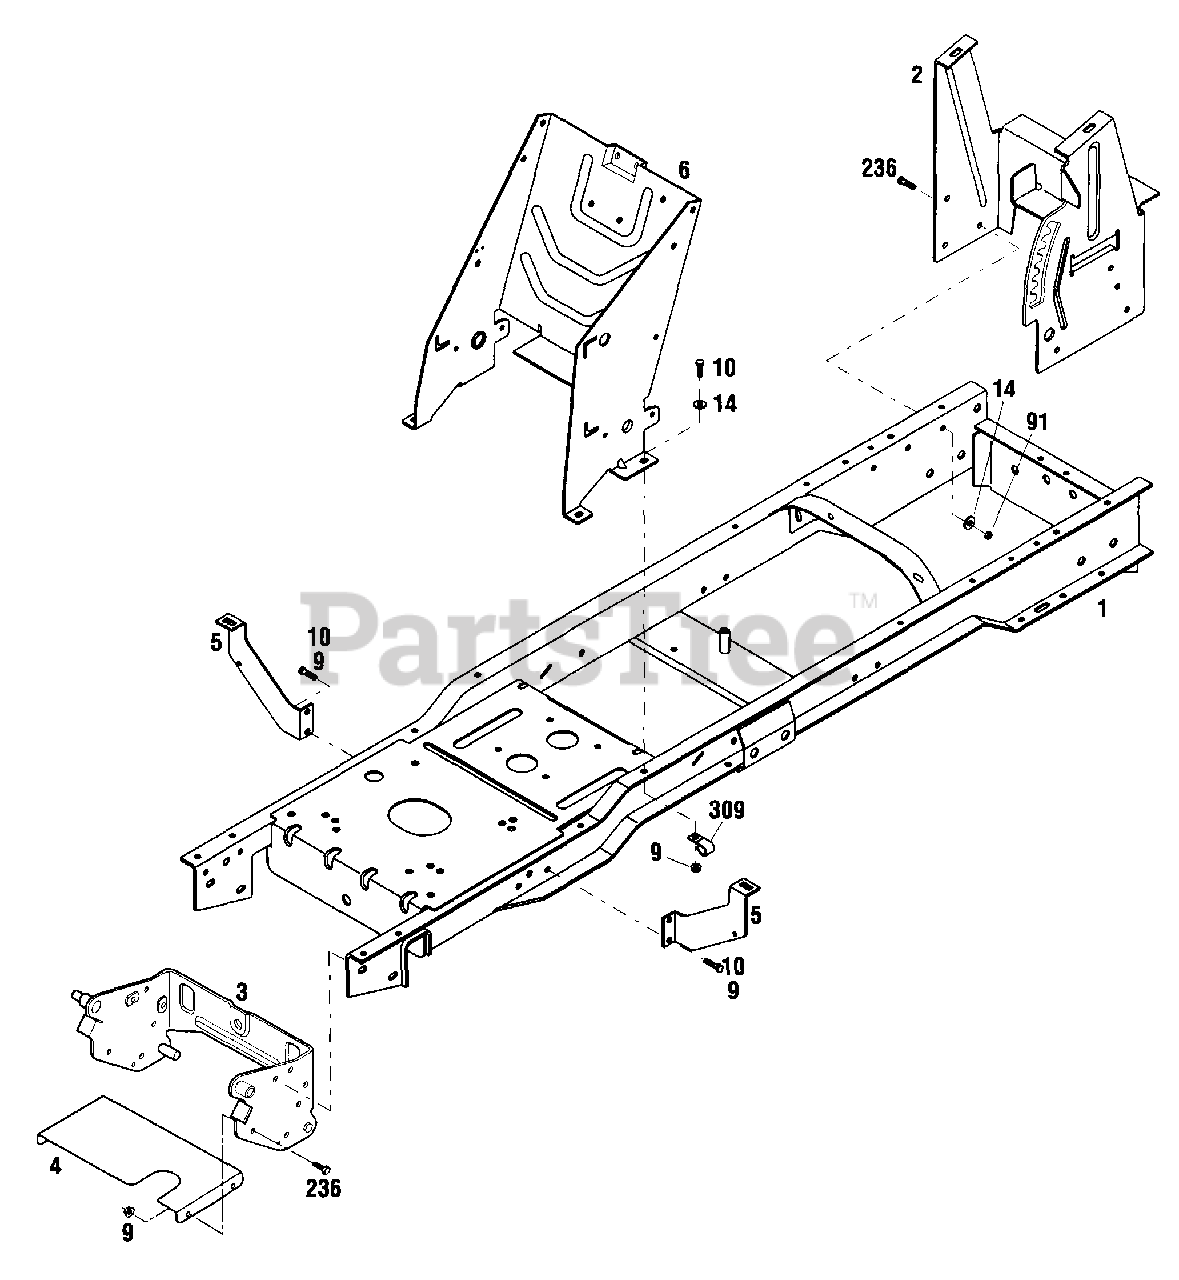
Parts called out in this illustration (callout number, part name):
1	Frame
2	Rear Tank Support
3	Attachment Bracket
4	Heat Shield
5	Fender Support
6	Console Support
9	Flange Nut, 5/16-18
10	Hex Head Screw, 5/16-18 x 3/4
14	Flat Washer, 5/16
91	Locknut, 5/16-18
236	Flange Screw, 5/16-18 x 3/4
